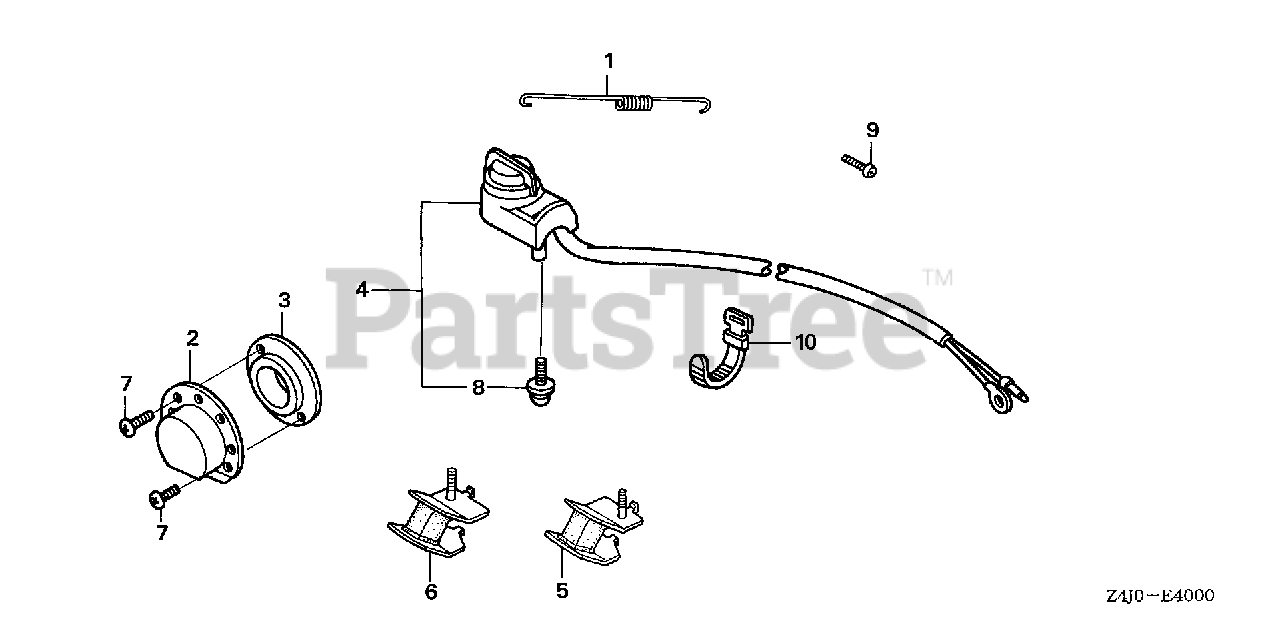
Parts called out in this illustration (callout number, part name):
2	DEFLECTOR
3	GUIDE, MUFFLER
7	SCREW, TAPPING (4X8)
